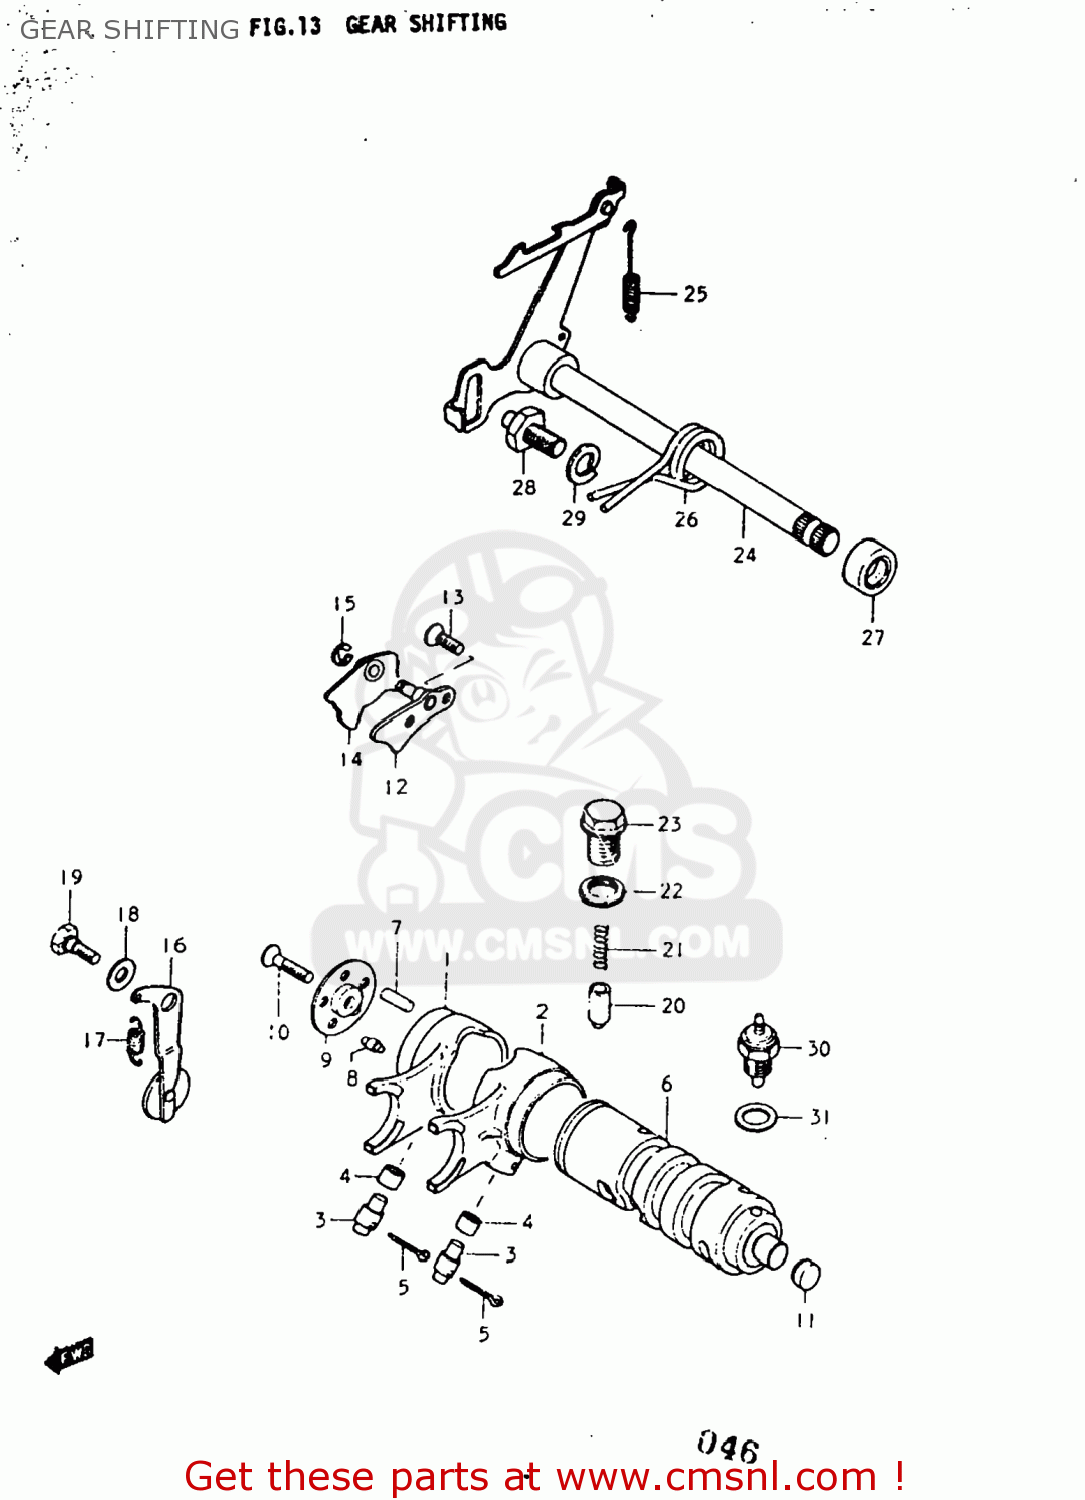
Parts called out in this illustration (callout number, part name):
1	FORK,GEAR SHIFT NO.1
2	FORK,GEAR SHIFT NO.2
3	PIN
4	SPACER
5	PIN 25X20
6	CAM,GEAR SHIFT
7	ROLLER(4X13.8)
8	PIN
9	RETAINER,GEAR SHIFT CAM DR PIN
10	SCREW
11	PLUG
12	GUIDE,GEAR SHIFT CAM
13	SCREW
14	PAWL,GEAR SHIFT CAM STOPPER
15	E RING
16	STOPPER,GEAR SHIFT CAM
17	SPRING
18	WASHER(6.5X16X2.3)
19	BOLT(6X16.1)
20	STOPPER,GEAR SHIFTING
21	SPRING
22	GASKET(14X19.2X2) (NAS)
23	BOLT,GEAR SHAFT CAM STOPPER
24	SHAFT,GEAR SHIFT
25	SPRING
26	SPRING
27	OIL SEAL
28	STOPPER,GEAR SHIFT ARM
29	LOCK WASHER
30	SWITCH ASSEMBLY,NEUTRAL INDICATOR
31	GASKET(12.5X20X1) (NAS)
